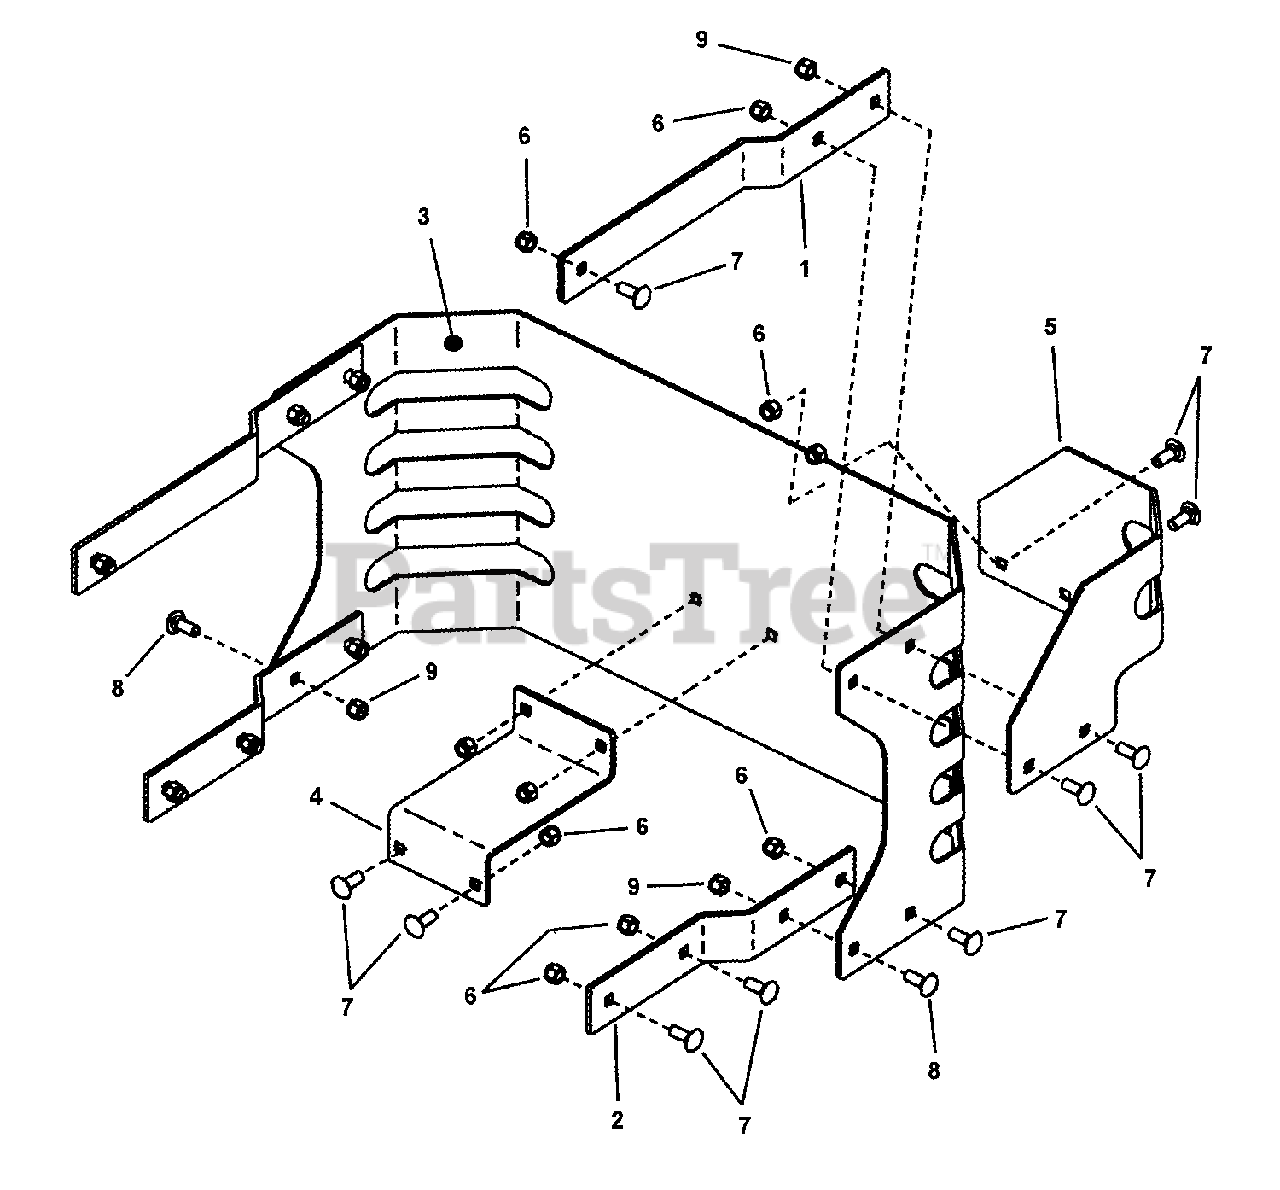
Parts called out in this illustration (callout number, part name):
1	UPPER BRACKET, Muffler Guard
2	MOUNT, Lower Muffler Guard
3	GUARD, Muffler (Back Plate)
4	REAR BRACE, Muffler Guard
5	GUARD, Muffler
6	NUT, 3/8-16 HEX NYLON LOCK
7	BOLT, 3/8-16 x 1" Square Neck Carriage, GR 5
8	BOLT, 3/8-16 x 3/4" Square Neck Carriage
9	NUT, 3/8-16 Hex Center Lock
